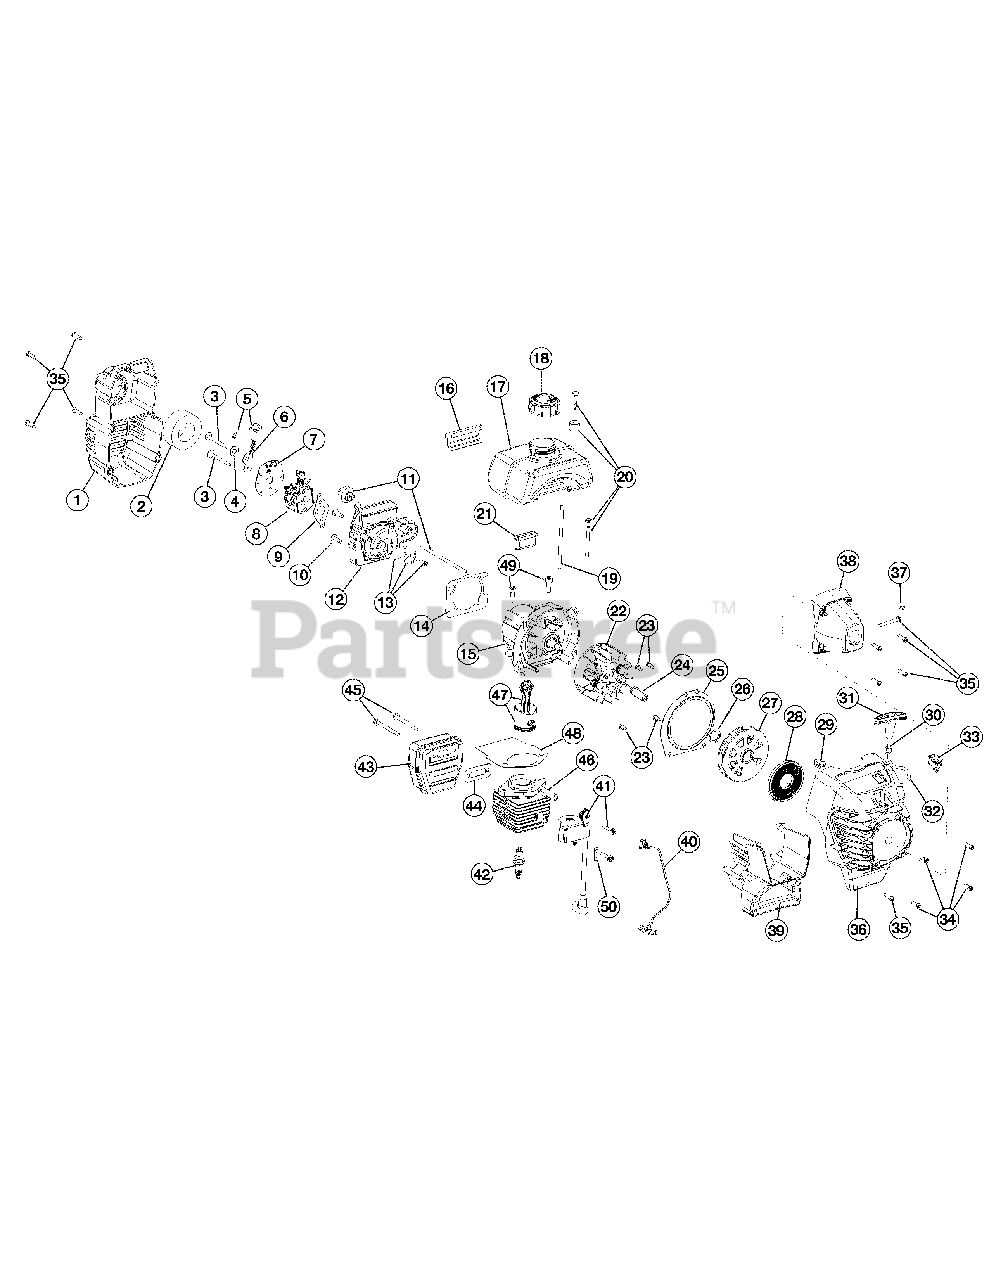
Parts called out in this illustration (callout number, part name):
1	Air Cleaner Cover Assembly
2	Air Cleaner Filter
3	Carburetor Mounting Screws
4	Wavey Washer
5	Choke Knob & Screw
6	Choke Lever Assembly
7	Choke Lever & Plate
8	Carburetor Assembly
9	Carburetor Gasket
10	Carb Mount Screw
11	Primer and Hose Assembly
12	Carburetor Mount Assembly
13	Reed Assembly
14	Carburetor Mount Gasket
15	Crankcase Service Assembly
16	Rear Mounting Pad
17	Fuel Tank Assembly
18	Fuel Cap Assembly
19	Fuel Return Line
20	Fuel Line Assembly
21	Front Mounting Pad
22	Flywheel Assembly
23	Screw
24	Square Nut Drive
25	Pulley Retainer Assembly
26	Palnut
27	Recoil Pulley Assembly
28	Recoil Spring
29	Rope Guide Retainer
30	Pull Handle
31	Rope Guide
33	Switch Assembly
34	Housing Screw
35	Cover Screw
36	Starter Housing Assembly
37	Anti-Rotation Screw
38	Clutch Cover Assembly
39	Shroud Extension and Stand
40	Wire Lead
41	Module Assembly
42	Spark Plug
43	Muffler Assembly
44	Exhaust Gasket
45	Muffler Mounting Bolt Assembly
46	Cylinder Assembly
47	Piston & Rod Assembly
48	Cylinder Gasket
49	Cylinder Bolt
50	Ground Tab
